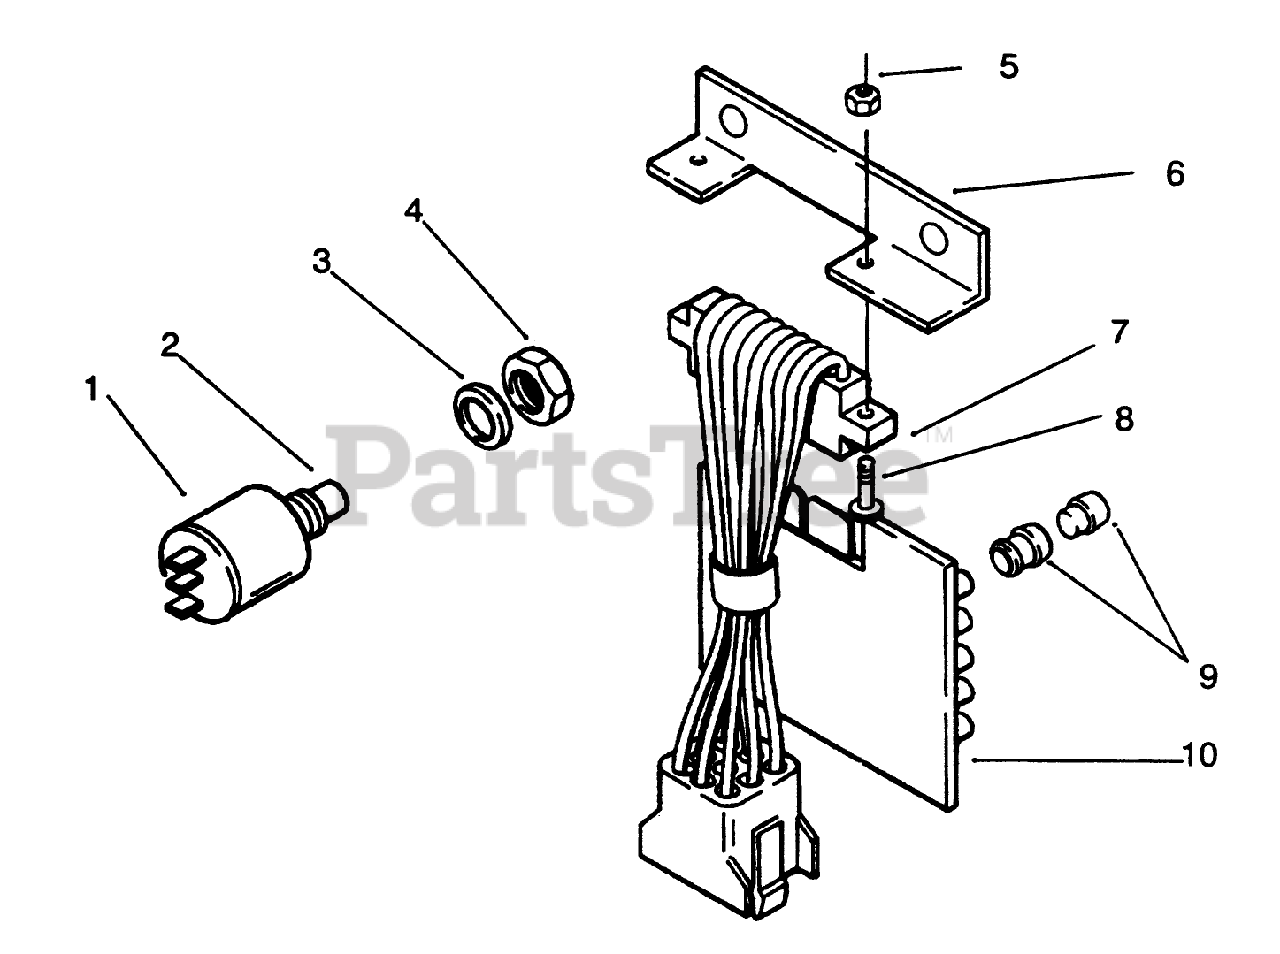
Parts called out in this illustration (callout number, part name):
1	SWITCH-PUSH BUTTON
4	NUT F/W 116796
5	NUT-HEX, NYL INS
6	BRACKET
7	P.C.-BOARD HARNESS
8	Screw
9	ASSY LENS & BUSHING
